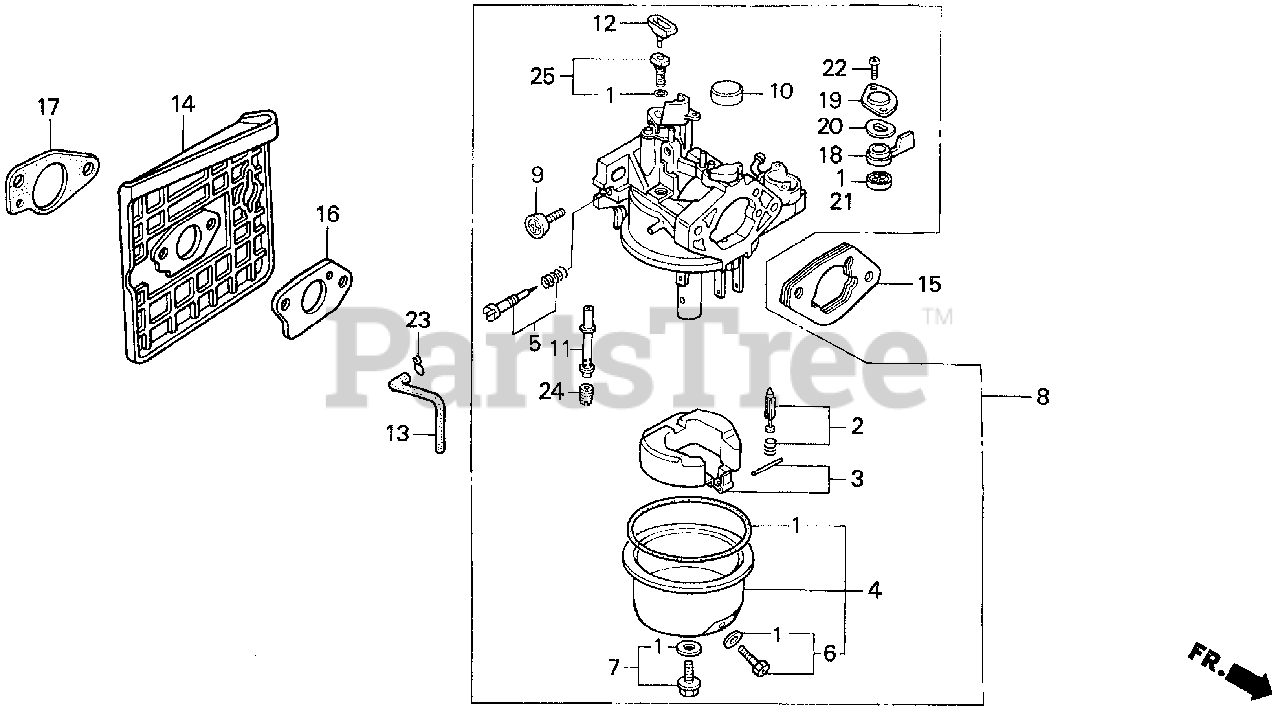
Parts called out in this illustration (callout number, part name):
1	GASKET SET
2	VALVE SET, FLOAT
3	FLOAT SET
4	CHAMBER SET, FLOAT
5	SCREW SET
6	SCREW SET, DRAIN
7	SCREW SET B
8	CARBURETOR ASSY. (BE32A A)
8	CARBURETOR ASSY. (BE32A C)
9	SCREW, THROTTLE STOP
10	CAP, CHOKE LEVER DUST
11	NOZZLE, MAIN
13	TUBE, AIR VENT (75MM)
14	INSULATOR, CARBURETOR
15	SPACER, CARBURETOR
16	GASKET, CARBURETOR (Honda Code 3134517). (NOT AVAILABLE)
16	GASKET, CARBURETOR
17	GASKET, INSULATOR (Honda Code 2271385). (NOT AVAILABLE)
17	GASKET, INSULATOR
18	LEVER, VALVE
19	PLATE, LEVER SETTING
20	SPRING, VALVE LEVER
21	GASKET, VALVE
22	SCREW, PAN (3X8)
23	CLIP, TUBE (B8)
24	JET, MAIN (#90)
24	JET, MAIN (#92)
24	JET, MAIN (#95)
25	JET SET, PILOT (#40)
